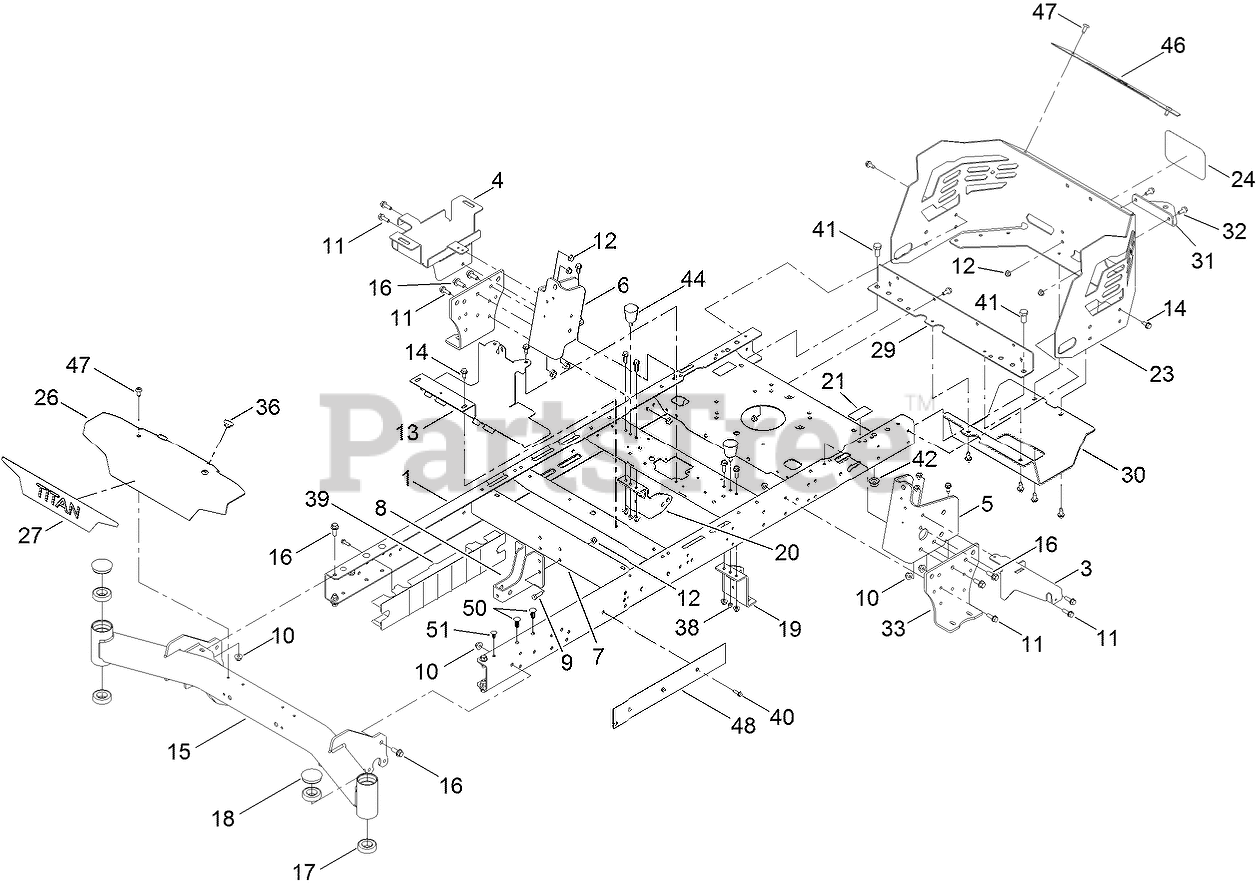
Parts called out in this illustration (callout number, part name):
1	FRAME ASM
3	BRACKET-SUPPORT, POD (LH)
4	TRAY-BATTERY
5	BRACKET-MOUNTING, LH
6	BRACKET-MOUNTING, RH
7	BRACE-CROSS, LOWER
8	BRACKET-MOUNT DAMPER, LOWER
9	SCREW-HH
10	NUT-HF, NI
11	SCREW-HHF
12	NUT-HF, NI
13	BRACKET-MOUNT
14	SCREW-HWHTF
15	FRONT AXLE ASM
16	SCREW-HHF
17	BEARING-BALL
18	CAP-GREASE
19	MOUNT-HYDRO, FRONT (LEFT)
20	MOUNT-HYDRO, FRONT (RIGHT)
21	DECAL-BYPASS
23	GUARD-ENGINE
24	DECAL
26	PLATE-FRONT
27	DECAL-TITAN
29	CROSSMEMBER-REAR, WIDE
30	GUARD-MUFFLER
31	BRACKET-HITCH
32	SCREW-HHF
33	MOUNT-HYDRO
36	BUMPER-SEAT
38	NUT-LOCK, NI
39	GUARD-RAIL
40	SCREW-HWH
41	SCREW-HH
42	NUT-LOCK
44	BUMPER-RUBBER
46	TRIM-GUARD, ENGINE
48	PLATE-FRAME
50	RIVET-PUSH
51	RIVET-PUSH
